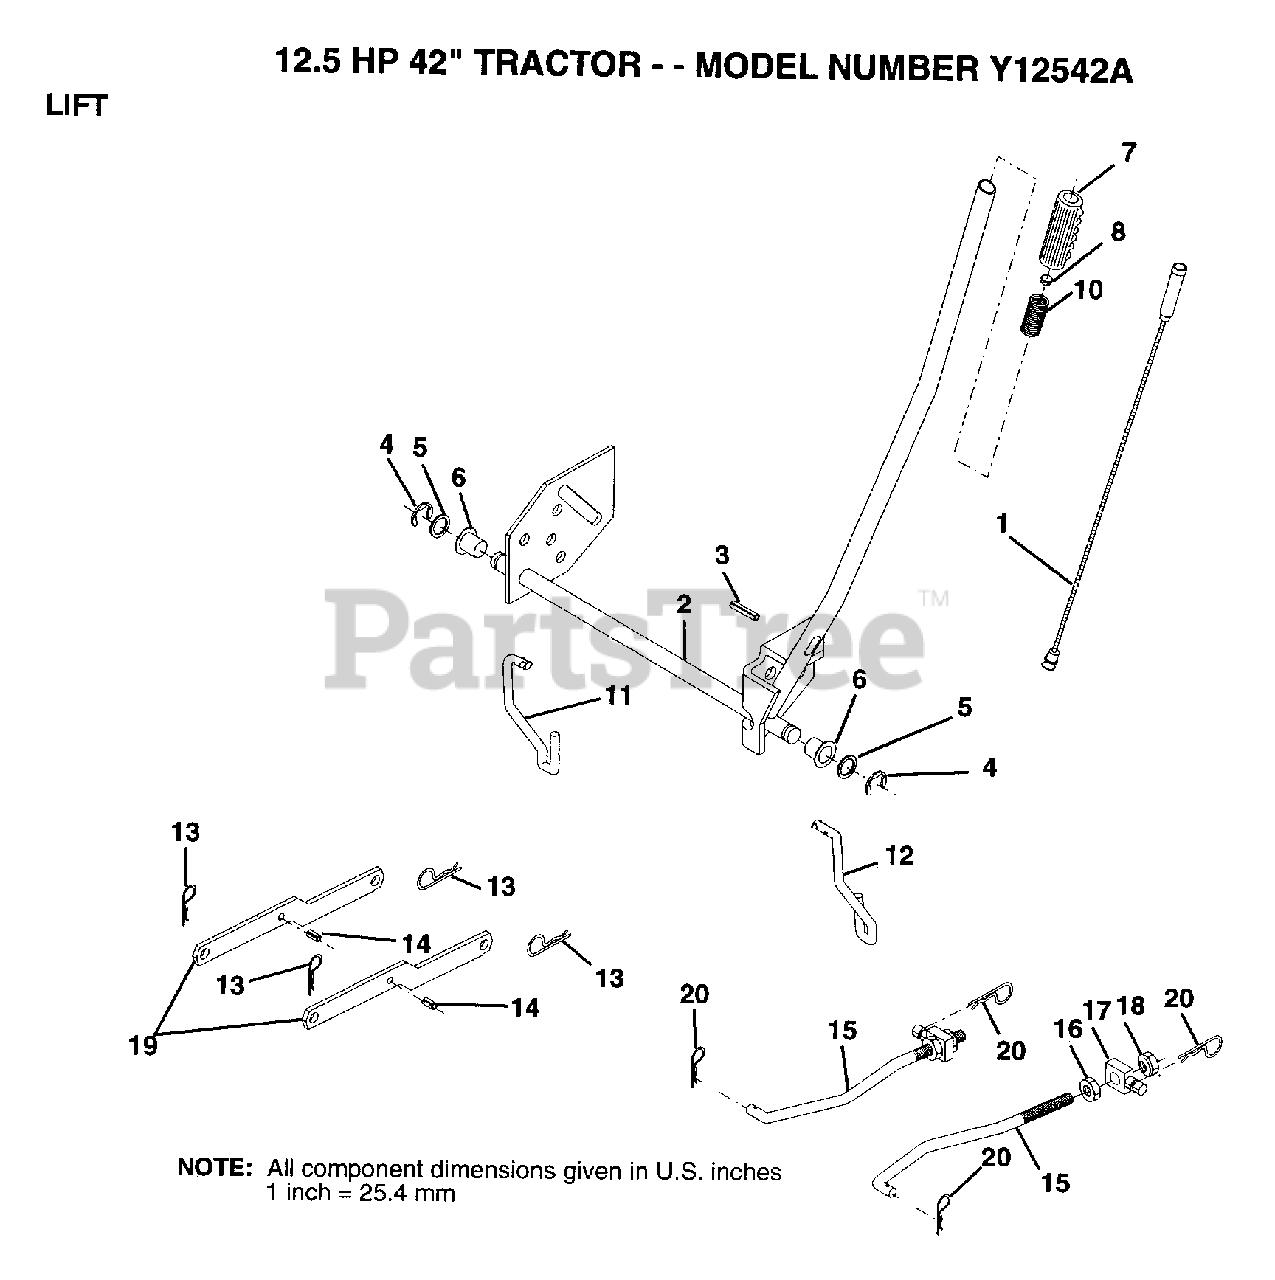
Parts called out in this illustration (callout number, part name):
1	WIRE ASM
3	PIN-GROOVE LT
5	WASHER
6	NYLON BEARING
7	GRIP
11	LINK LIFT LH
12	LIFT LINK RH
14	"PIN,SPRING"
15	LINK.FRONT
16	NUT
17	TRUNION
18	NUT.LK.W/WSH.1/2.
20	RETAINER.SPRING
